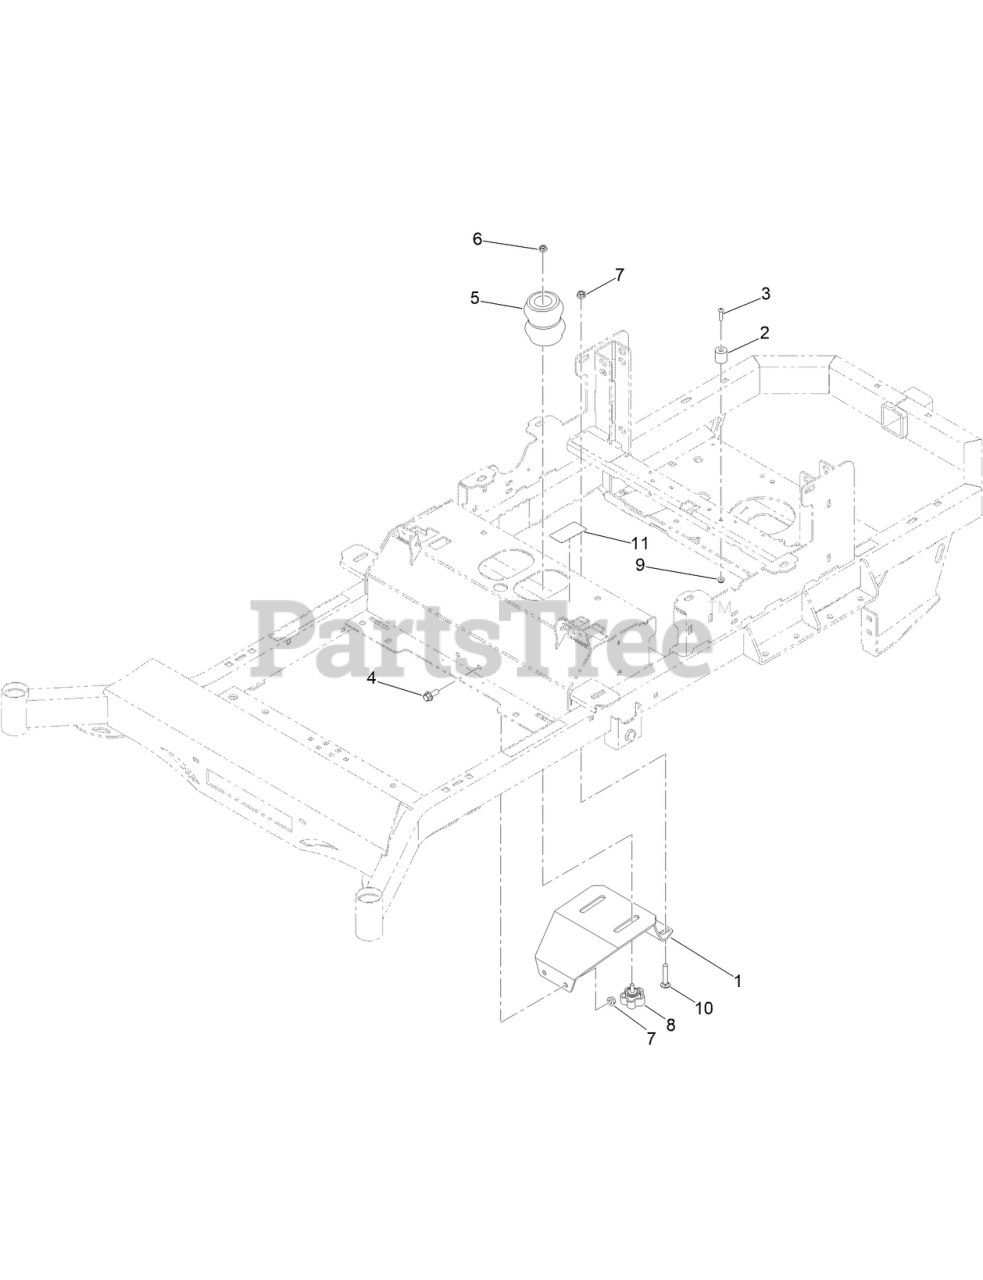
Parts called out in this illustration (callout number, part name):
1	MWR SEAT SUSP BRKT BLACK
2	HOOD REST RUBBER BUMPER
3	1/4-20 X 1 BUTTON SOCKET C/S 18-8 SS
4	SCREW-HHF
5	SRT RR SUSP AND SEAT FT ELASTOMER TCB-3
6	5/16-18 HEX SERRATED LG FLANGE L/NUT ZC
7	3/8-16 HEX FLANGE NUT W/SERR ZINC YELLOW
8	5/16-18X3/4 SL 5-LOBE MALE KNOB 1.90 DIA
9	NUT-HF
10	SCREW-CARR
11	DECAL-WEIGHT, SEAT
